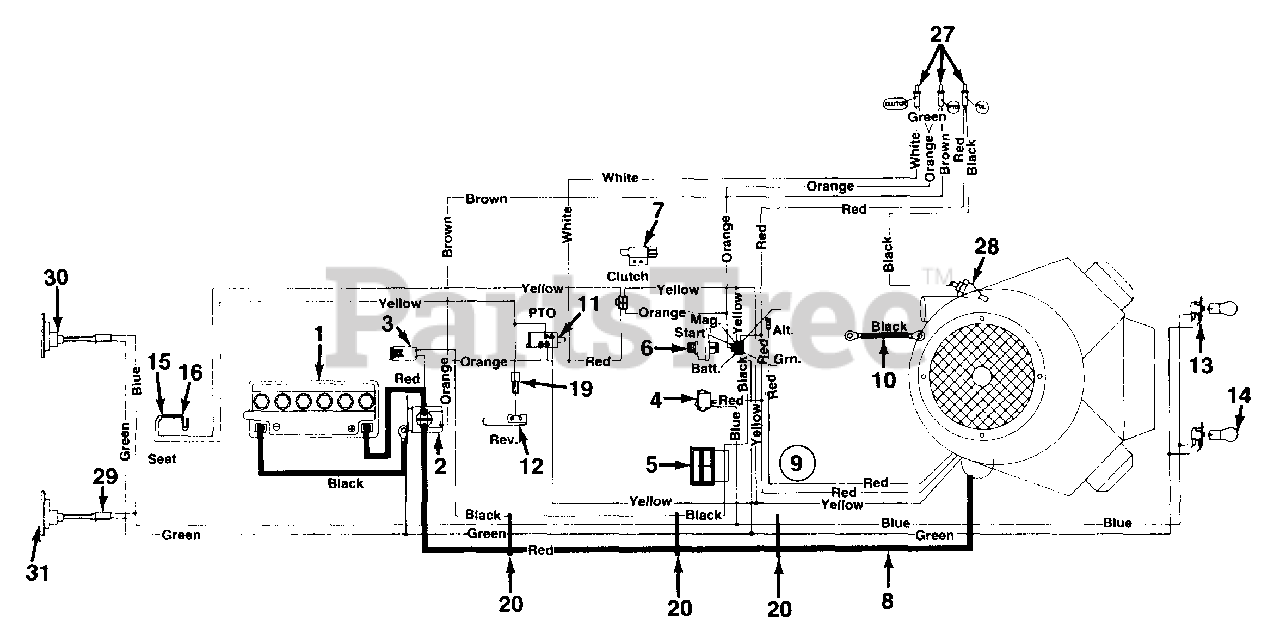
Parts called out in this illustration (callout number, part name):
1	Battery - 12V
2	Solenoid
3	Fuse 20 Amps
4	Light Switch
5	Ammeter
6	Ignition Switch
7	Safety Switch (Clutch)
8	Electric Wire - 30.0" Lg.
9	Wire Harness w/o Taillights
10	Ground Wire - 7.5" Lg.
11	Safety Switch (Deck)
12	Safety Switch (Reverse)
13	Headlight Socket
14	Headlight Bulb
15	Safety Switch (Seat)
16	Safety Switch (Seat)
19	Ext. Wire
20	Cable Tie
27	Bulb
28	Oil Pressure Switch
29	Taillight Harness
30	Taillight
31	Taillight Bulb
